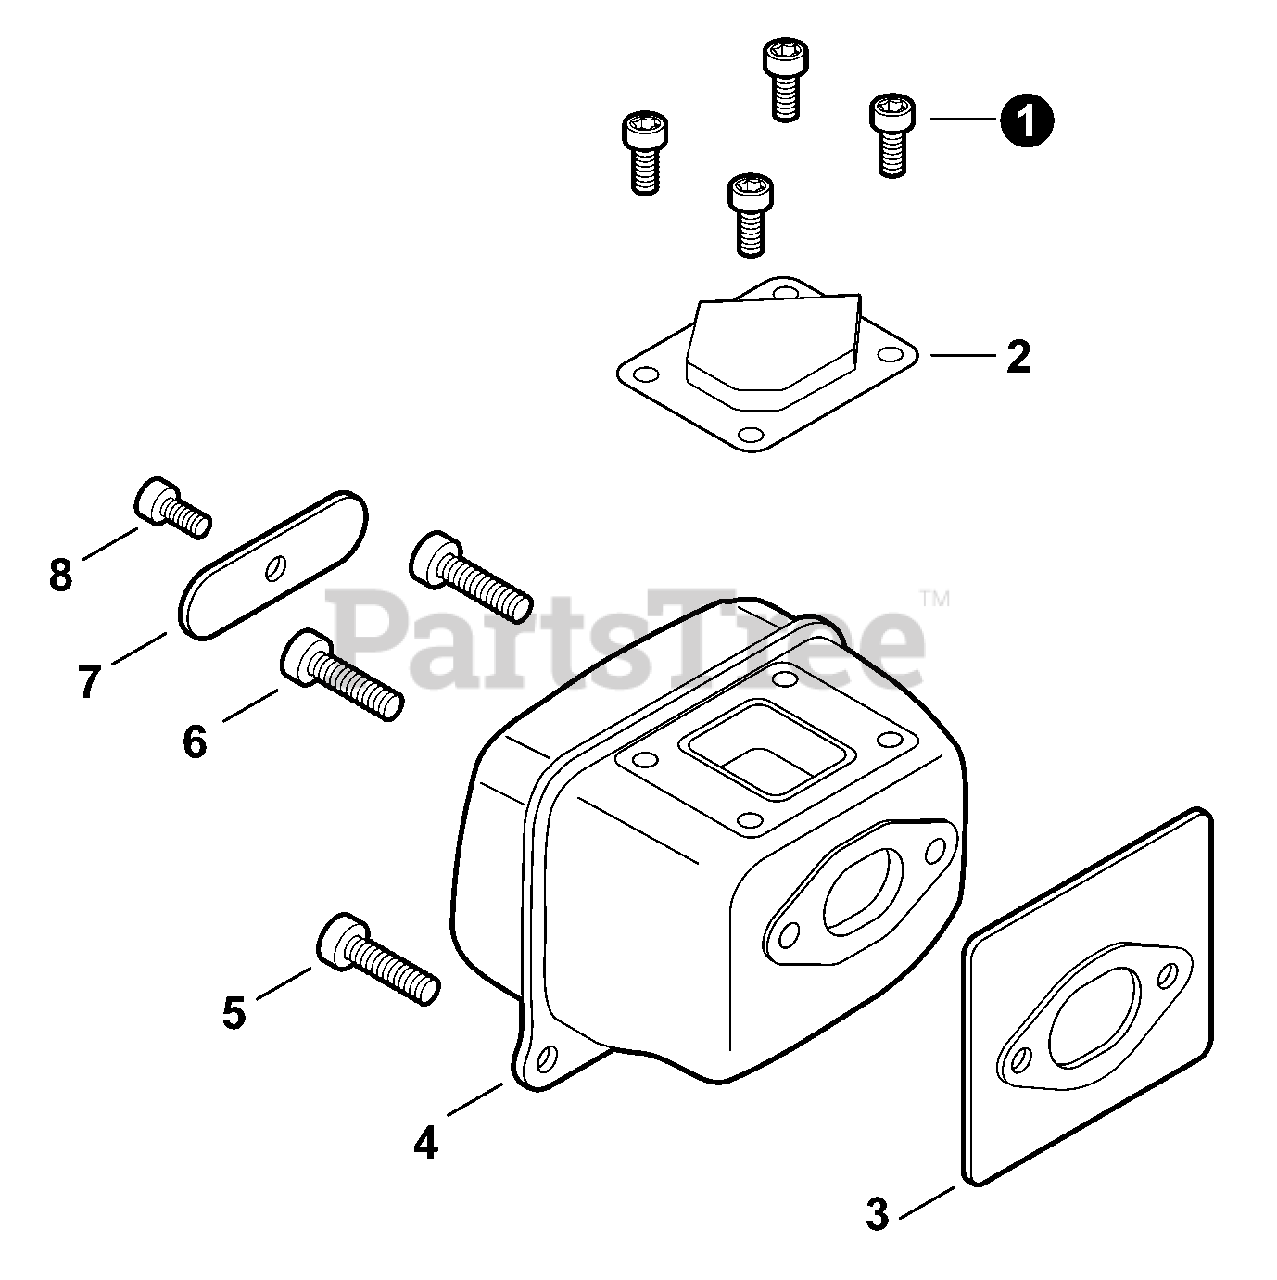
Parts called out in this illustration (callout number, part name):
1	BOLT, TORX 4×8
2	GUIDE, EXHAUST
3	GASKET, EXHAUST
4	MUFFLER
5	BOLT, TORX 5×20
6	BOLT, TORX 5×20
7	PLATE, MUFFLER
8	BOLT, TORX 4×8
